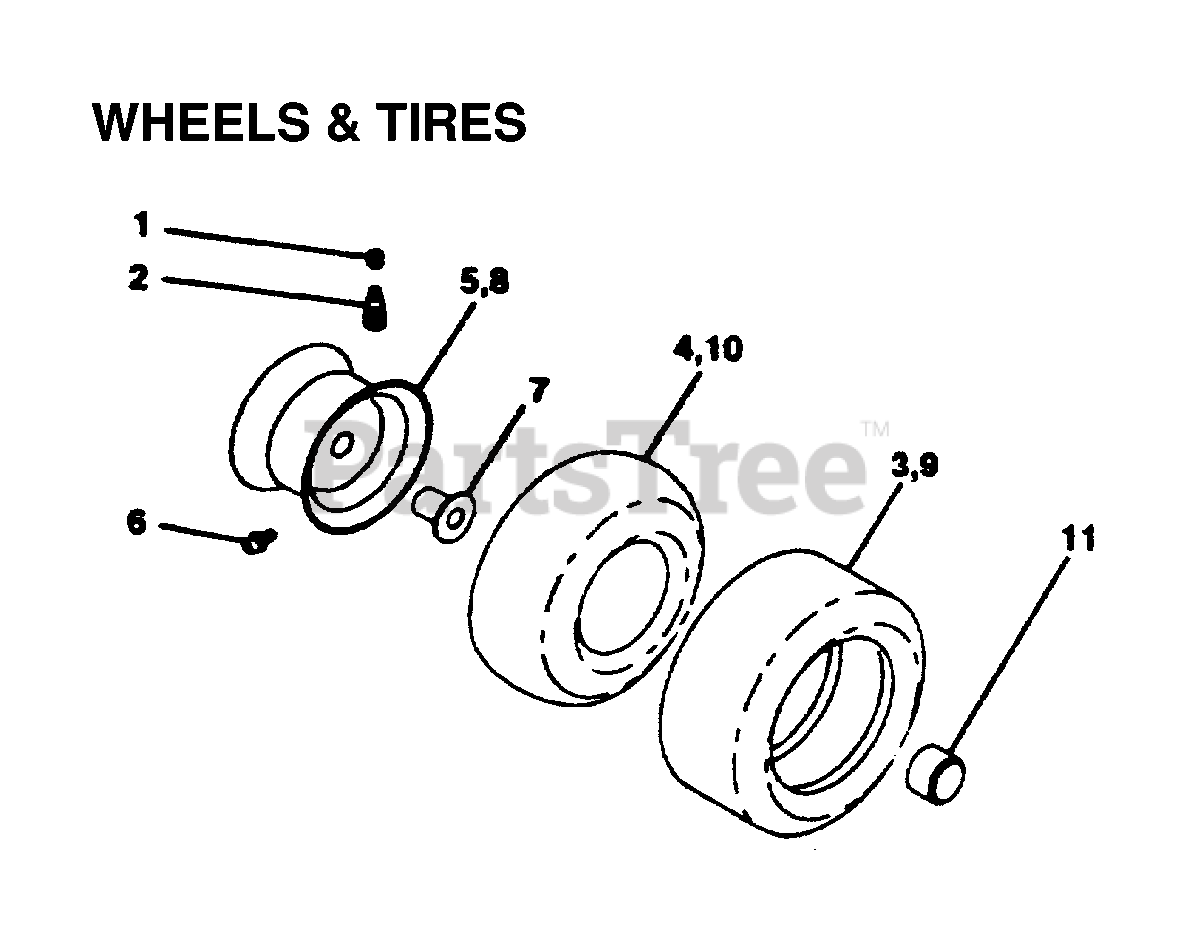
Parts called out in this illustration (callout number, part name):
2	VALVE STEM LT
3	TIRE HEAVY DUTY
4	TUBE.5.3/4.5/6
5	RIM ASM 6" FRONT SILVER
6	FITTING LT
7	BEARING T
8	RIM ASM 8" REAR SILVER
9	TIRE.TS.20X10-8
10	TUBE - UNIVERSAL FOR 8" RIM
11	CAP.HUB.FRONT.LT.BLACK
